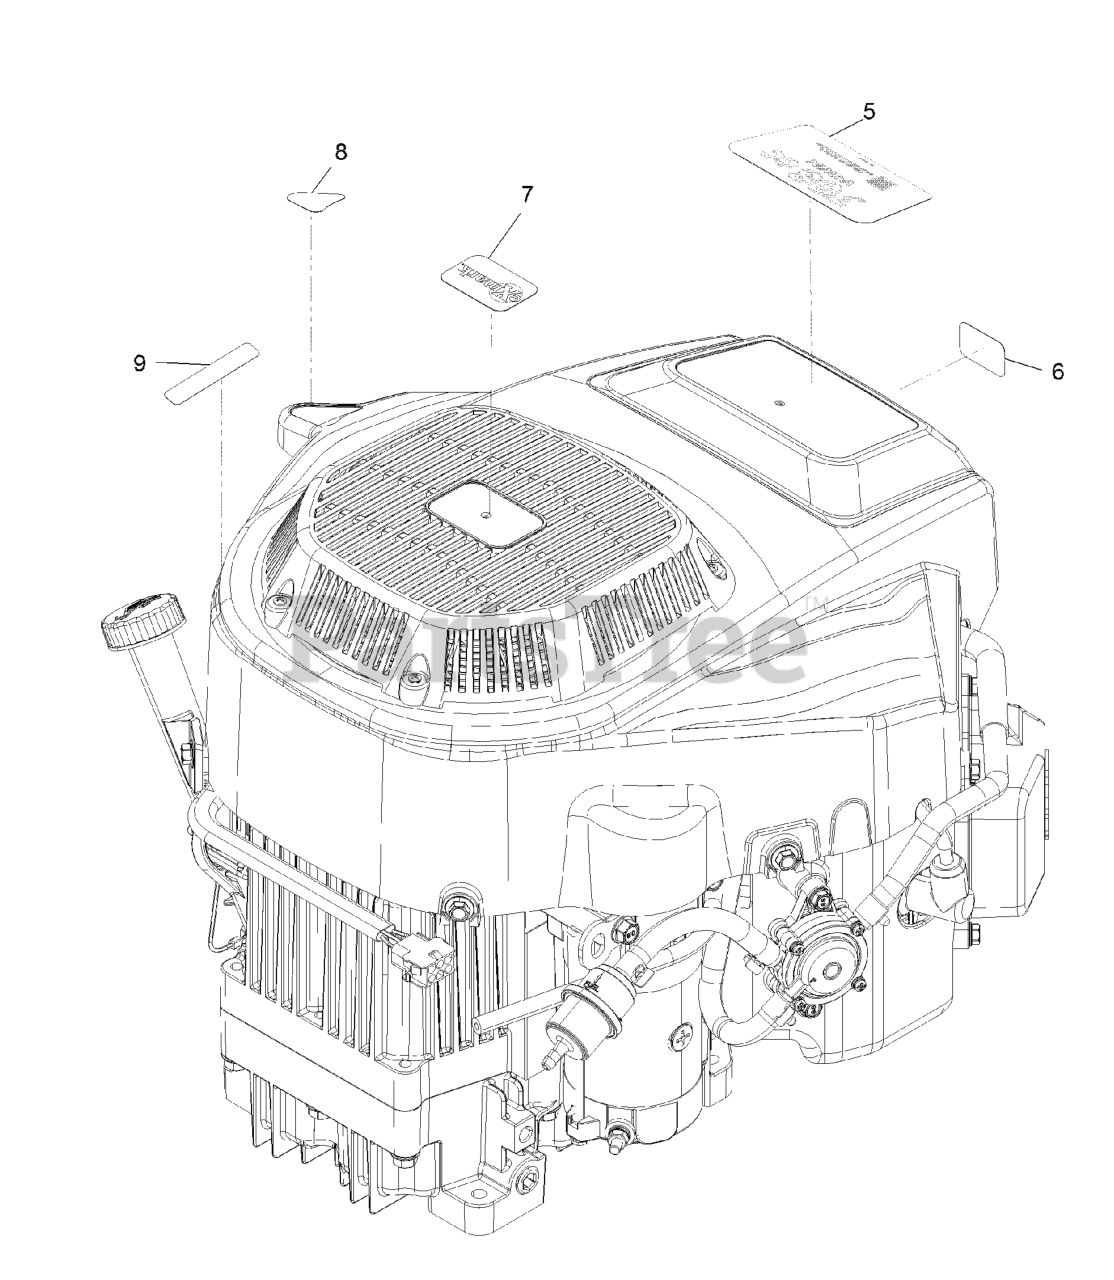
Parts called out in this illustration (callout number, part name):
5	DECAL-ENGINE DISPLACEMENT
6	PLACARD-INTAKE, EXMARK
8	DECAL-DRAIN, OIL
9	DECAL-SHUTDOWN
